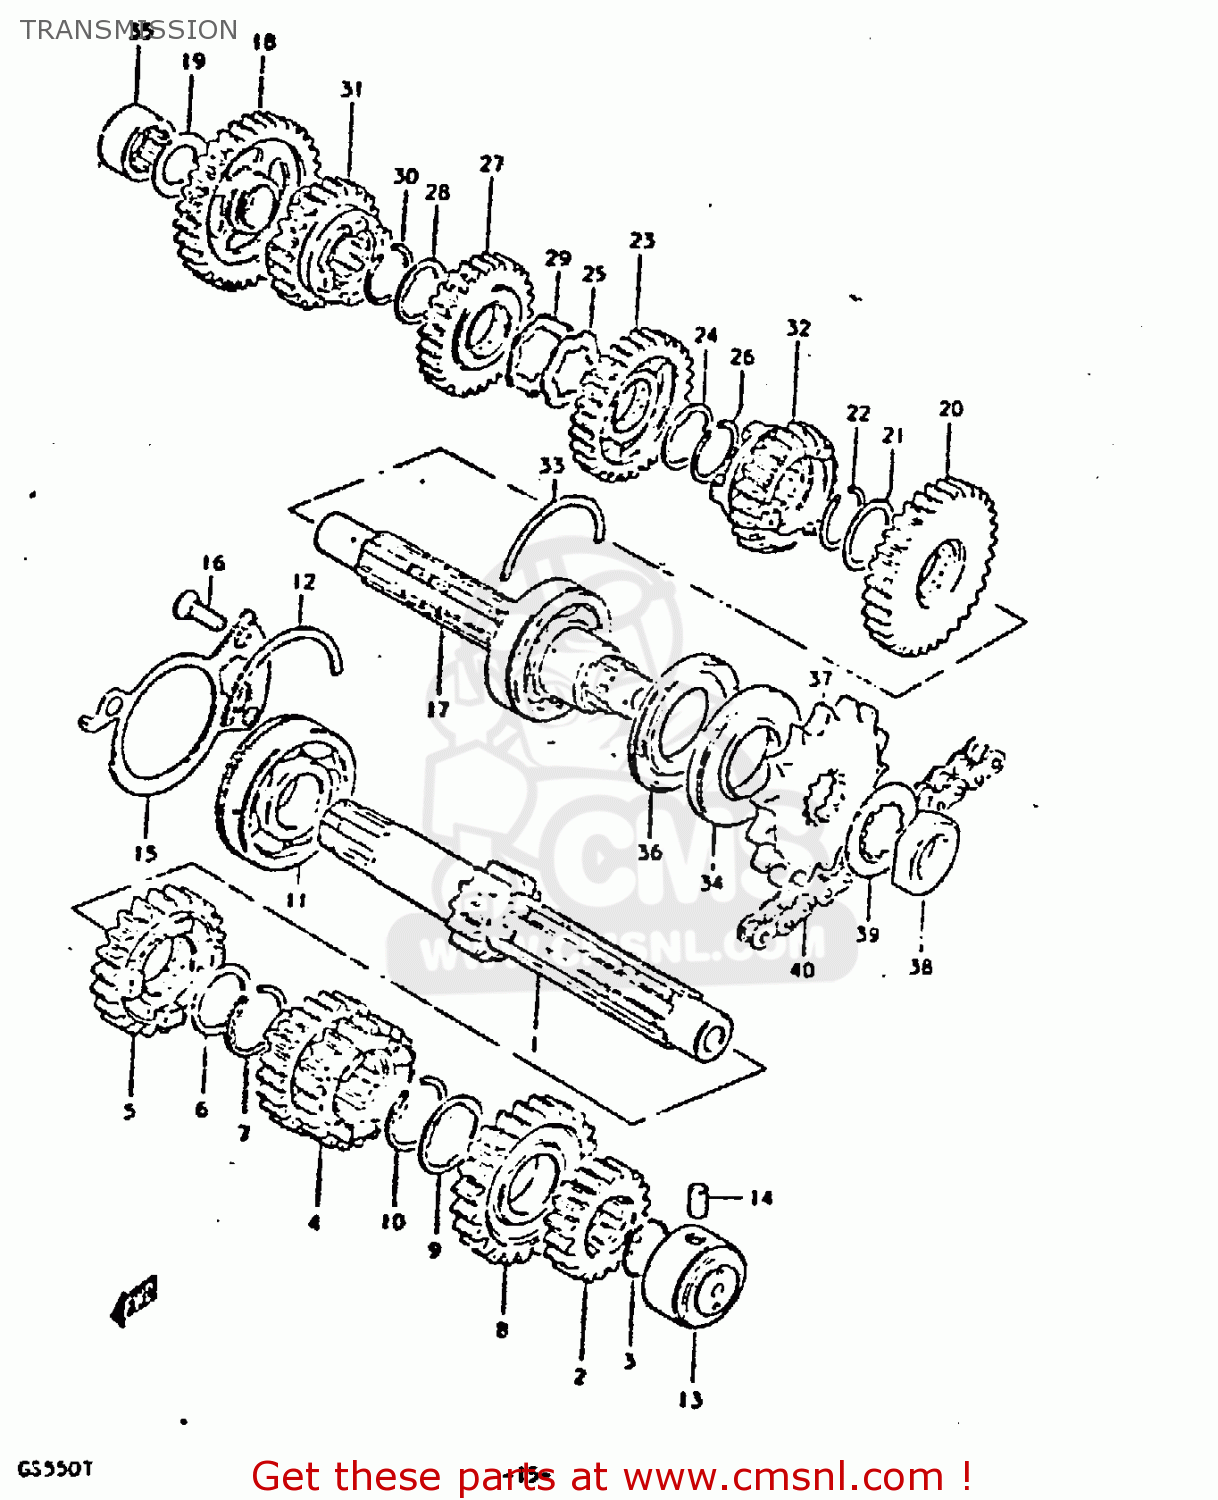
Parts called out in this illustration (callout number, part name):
1	SHAFT,COUNTER
2	GEAR,SECOND DRIVE
3	RING,SNAP
4	GEAR,THIRD DRIVE
5	GEAR,FIFTH DRIVE
6	WASHER
7	CIRCLIP
8	GEAR,SIXTH DRIVE
9	WASHER,LOCK
10	CIRCLIP
11	BEARING(25X62X17)
12	C-RING
13	BEARING
14	PIN
15	PLATE,COUNTERSHAFT BEARING
16	SCREW
17	SHAFT,DRIVE
18	GEAR,FIRST DRIVEN
19	WASHER
20	GEAR,SECOND DRIVEN
21	WASHER
22	CIRCLIP
23	GEAR,THIRD DRIVEN
24	WASHER,LOCK
25	WASHER,LOCK
26	CIRCLIP
27	GEAR,FOURTH DRIVEN
28	WASHER,LOCK
29	WASHER
30	CIRCLIP
31	GEAR,FIFTH DRIVEN
32	GEAR,SIXTH DRIVEN
33	C-RING
34	OIL SEAL
35	ROLLER BEARING (20X34X1
36	SEAL,OIL(32X62X5.5)
37	SPROCKET,ENGINE
38	NUT
39	WASHER
40	CHAIN ASSEMBLY,DRIVE
